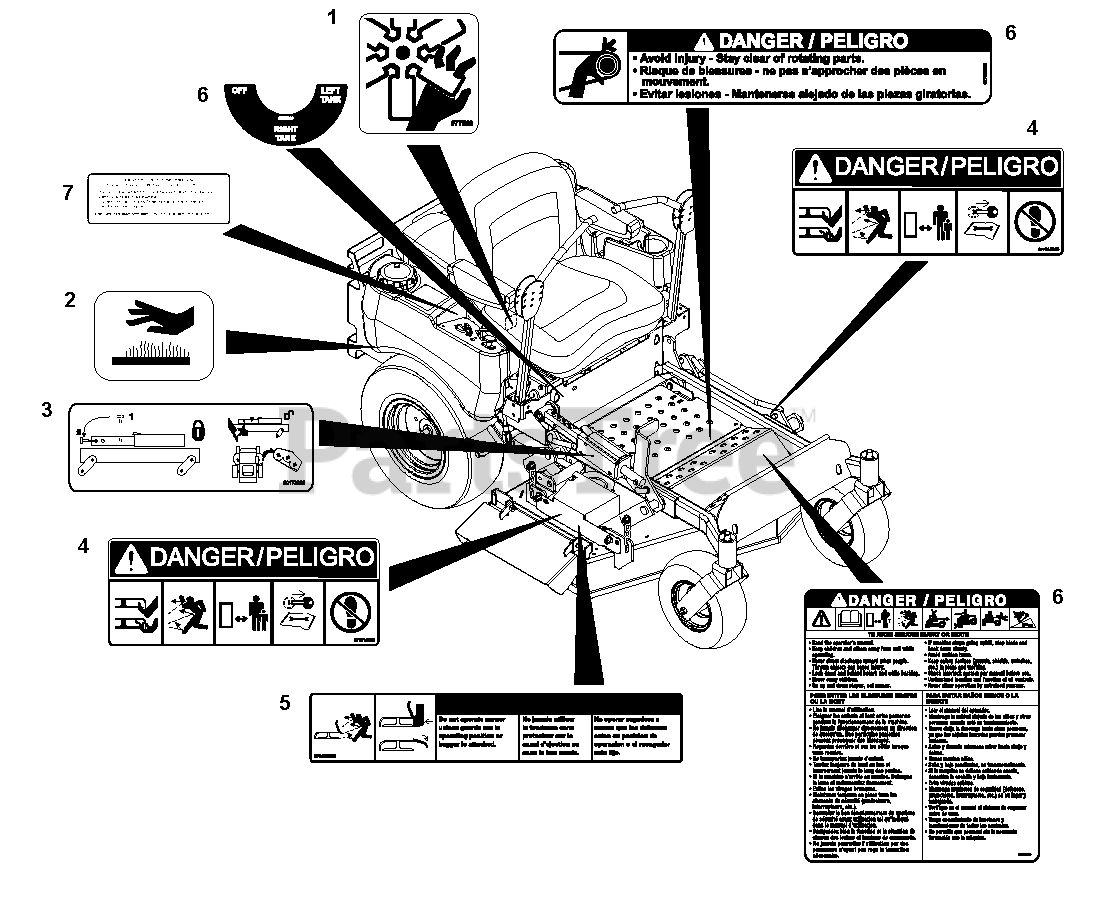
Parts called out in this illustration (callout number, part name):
1	Decal, Danger Fan
2	Decal, Hot Surface
3	Decal, Deck Service
4	Decal, Mower Pan Head Danger
5	Decal, Warning
6	Set, Decal Common Danger/Fuel
7	Decal, EPA (S/N 2500 and up)
